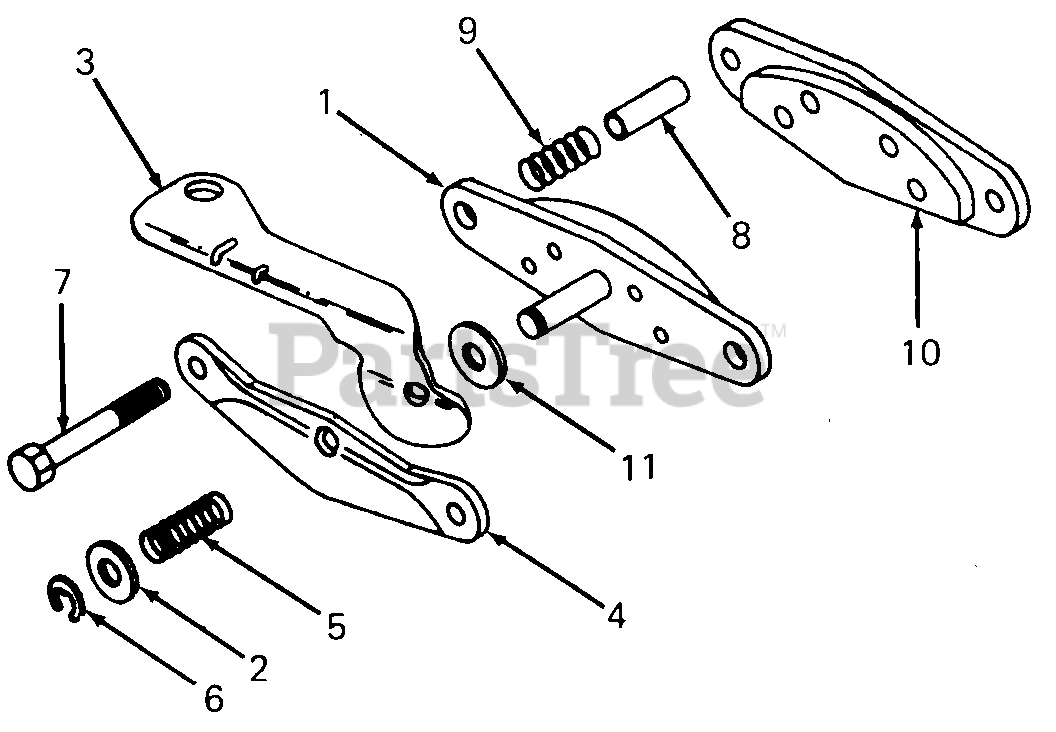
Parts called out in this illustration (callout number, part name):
1	Plate Assy, Stud
2	Washer, Thrust
4	Plate, Actuator
5	Spring, Compression
6	Ring, Retaining
7	Screw, Hex Cap, 1/4-20 X 2.0 Lg
9	Spring, Return
10	Slide Assy, Carrier
